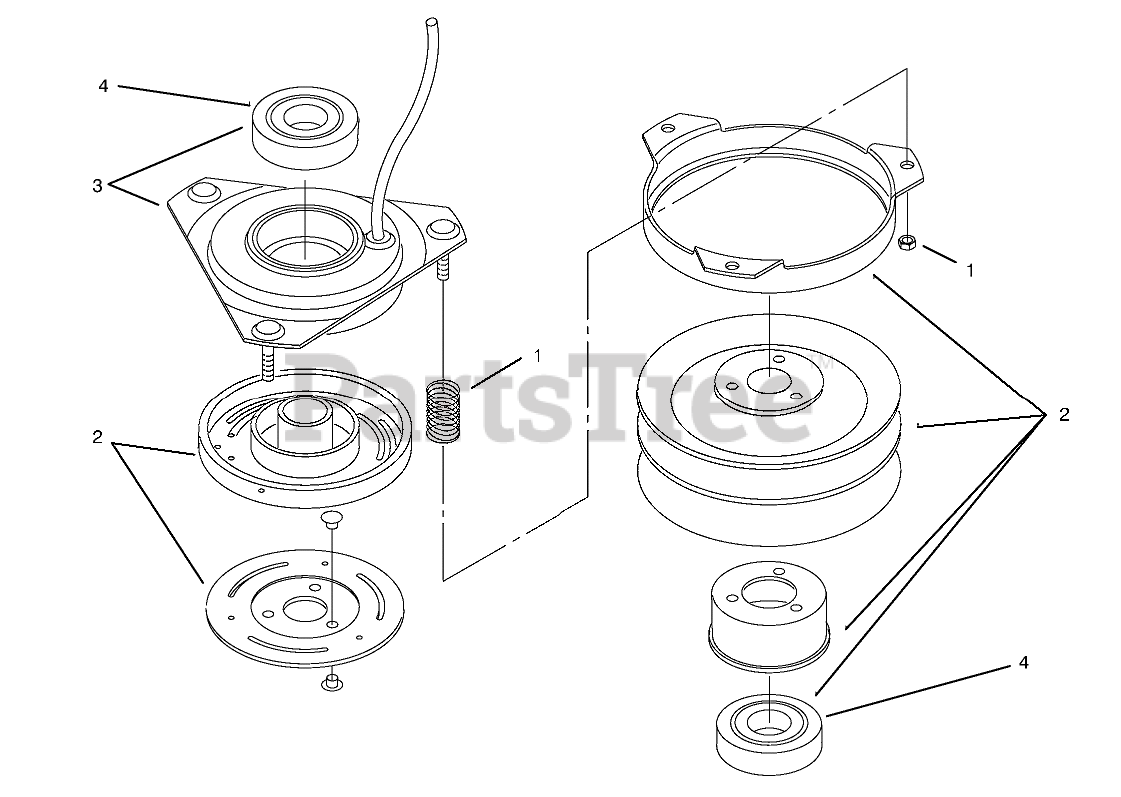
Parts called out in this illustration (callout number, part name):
1	ACCESSORY PKG SRVC PART
2	Rotor ASM w/Bearing (Only On: 72104)
2	Rotor & Armature ASM (Only On: 72085)
3	FIELD ASSY (SRVC PART)
4	BEARING-ELEC CLUTCH
